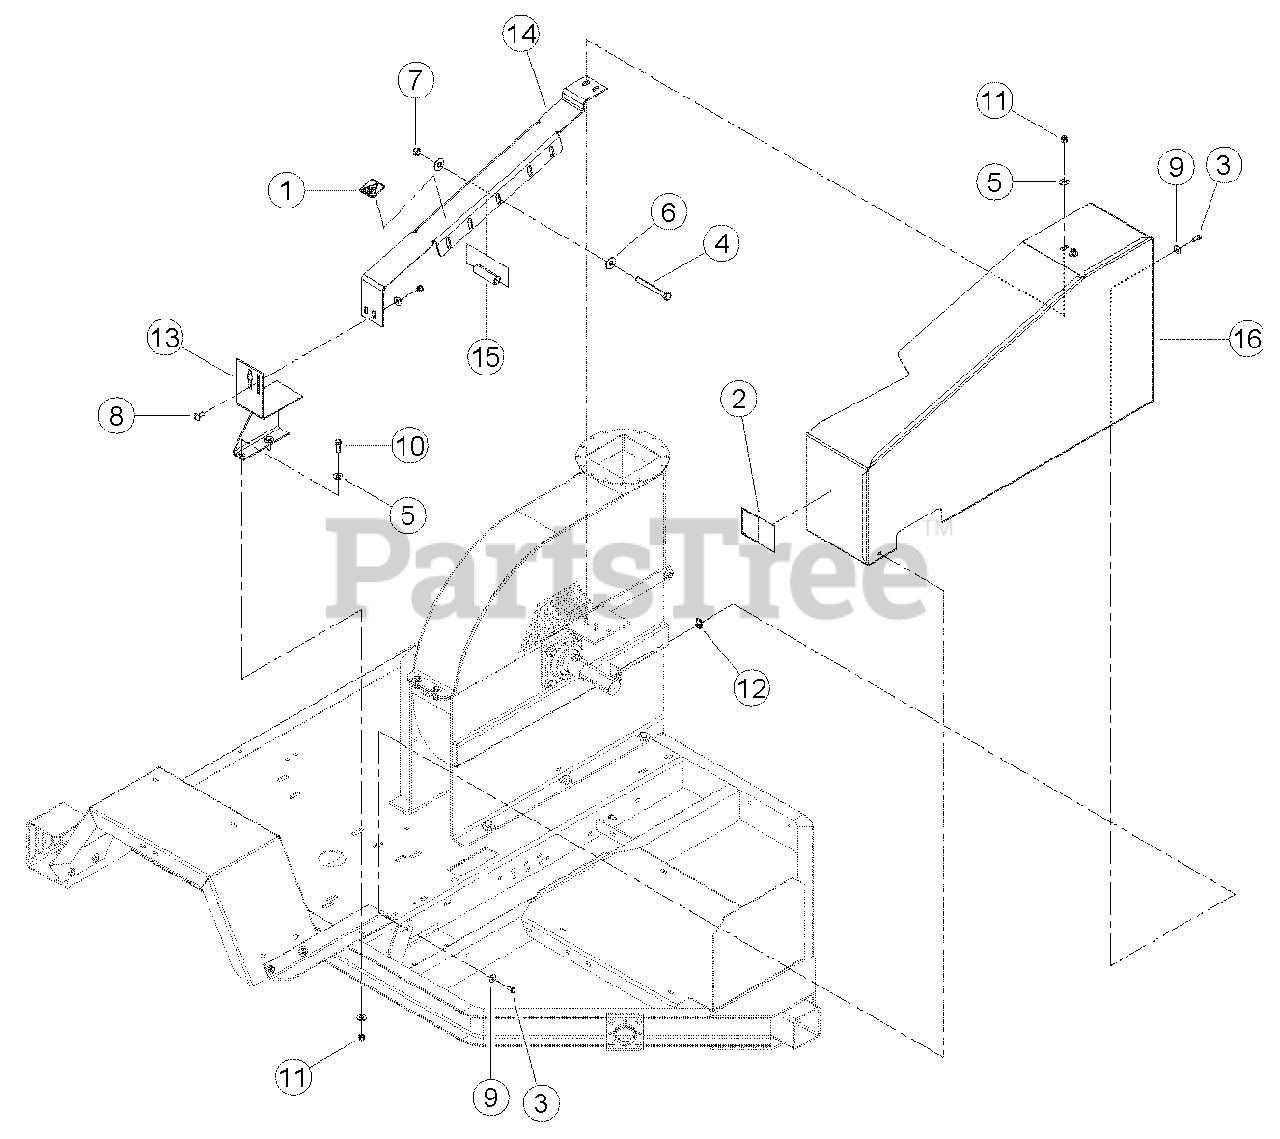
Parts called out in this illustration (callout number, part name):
1	DECAL, SHIELD DANGER ISO
2	DECAL, CLUTCH ENGAGEMENT ISO
3	BOLT, 5/16 X 3/4 HEX HD GR5 ZP
4	BOLT, 1/2 X 4-1/2 HHCS GR5 NC ZP
5	WASHER, 3/8 FLAT ZP
6	WASHER, 1/2 FLAT ZP
7	NUT, 1/2 CENTERLOCK GRB ZP
8	BOLT, 3/8 X 1 CRG GR5 ZP
9	WASHER, 5/16 FLAT ZP
10	BOLT, 3/8 X 1-1/4 HEX HD GR5 ZP
11	NUT, 3/8 NE NYLOCK ZP
12	NUT, 5/16-18 TINNERMAN U-TYPE
13	WELDMENT, BELT GUIDE
14	SHIELD, BELT
15	SPACER, TUBE 1 OD X .5 ID X 3.13
16	WELDMENT, 50 HP BELT GUARD
